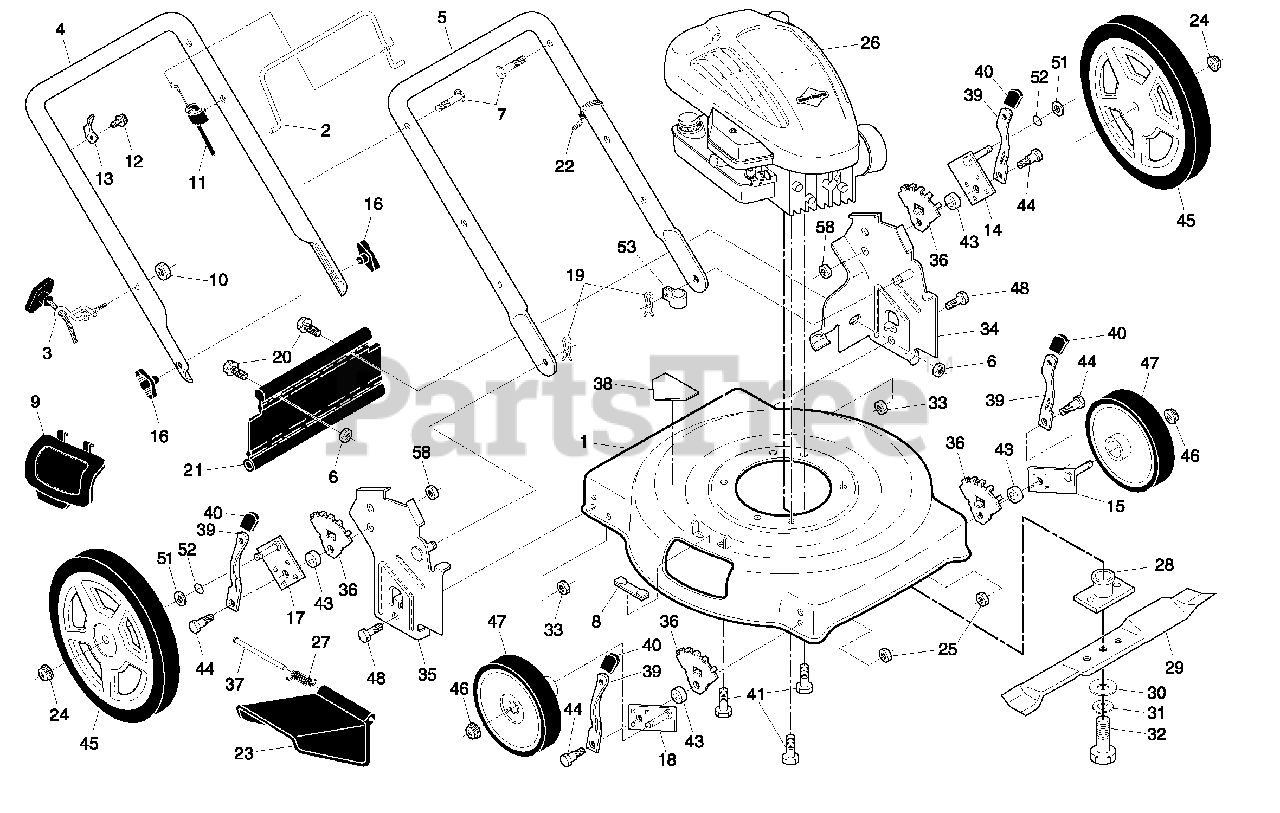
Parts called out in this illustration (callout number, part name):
1	Lawn Mower Housing
2	Control Bar
3	Rope Guide
4	Upper Handle
5	Lower Handle
6	Locknut, Hex 1/4-20
7	Handle Bolt 5/16-18
8	Clip, Closeout
9	Mulcher Plate
10	Nut, Hex 1/4-20
11	Engine Zone Control Cable
12	Hex Washer Head Screw #10-24 x 1/2
13	Up-Stop Bracket
14	Axle Arm Assembly, Rear, LH
15	Axle Arm Assembly, Front, LH
16	Knob, Handle
17	Axle Arm Assembly, Rear, RH
18	Axle Arm Assembly, Front, RH
19	Hairpin Cotter
20	Screw, Hex Cap Head 1/4-20
21	Rear Deflector
22	Wire Tie
23	Discharge Guard
24	Nut, Hex, Flangelock 3/8-16
25	Nut, Hex, Flangelock 5/16-18
27	Torsion Spring
28	Blade Adapter
29	22" Blade
30	Hardened Washer
31	Helical Lockwasher 3/8
32	Screw, Hex Head, Grade 8, 3/8-24 x 1-3/8
33	Nut, Hex, Nylock 5/16-18
34	Handle Bracket, LH
35	Handle Bracket, RH
36	Wheel Bracket Adjuster
37	Hinge Rod
38	Danger Decal
39	Selector Spring
40	Selector Knob
41	Screw, Hex Head, Threaded, Rolled 3/8-16 x 1
43	Spacer
44	Shoulder Bolt 5/16-18
45	Wheel & Tire Assembly, Rear, 12"
46	Nut, Hex, Flangelock 3/8-16
47	Wheel & Tire Assembly, Front, 8"
48	Bolt, Hex Head 5/16-18
51	Washer, Flat 3/8
52	O-Ring
53	Clip, Cable
58	Nut, Hex
58	Operator's Manual, English
58	Operator's Manual, Spanish
58	Repair Parts Manual
